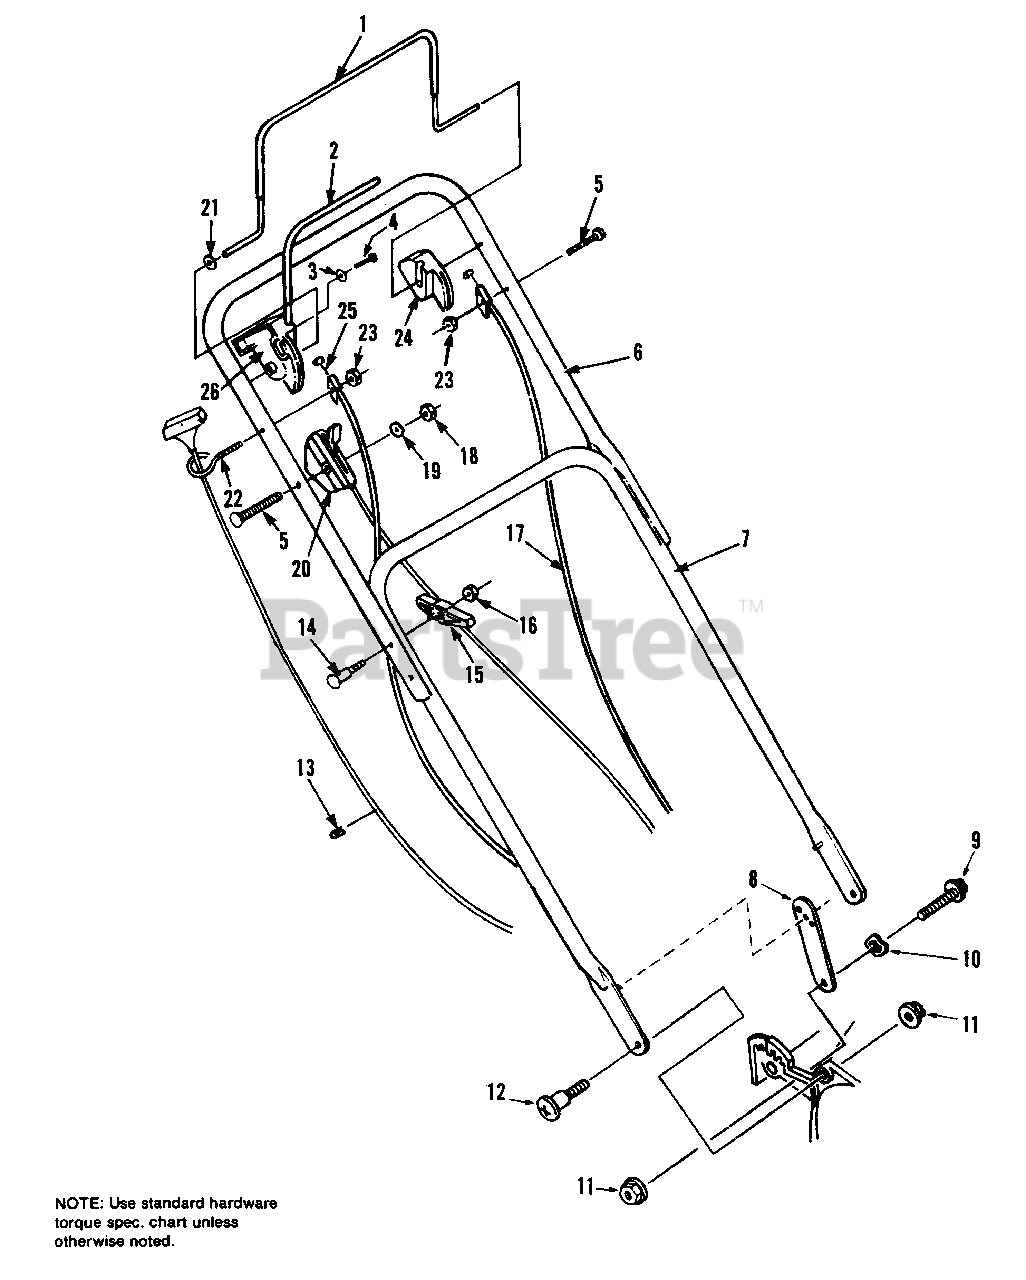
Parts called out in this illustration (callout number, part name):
1	BAIL, Brake Control
2	TRACTION LEVER
3	WASHER, #10
4	SCREW, Hex Hd., #10-16 x 1/2
5	SCREW, Truss Hd., Phillips (Qty. 1 on 1691922)
6	HANDLE, Upper
7	HANDLE, Lower, w/Pin
11	NUT, Hex, Flange, 5/16-18
13	STOP, Rope
14	BOLT
15	KNOB, Handle
16	NUT, Hex Locking, 5/16-19
17	CONTROL, Engine
18	NUT, Hex, 1/4-20
20	CONTROL, Throttle
21	WASHER, 5/16
22	EYEBOLT, 1/4-20 x 1-3/4
23	NUT, Hex, 1/4-20 (Qty. 1 on 1691922)
24	ACTUATOR, L.H.
25	CONTROL, Engine
26	ACTUATOR, R.H.
